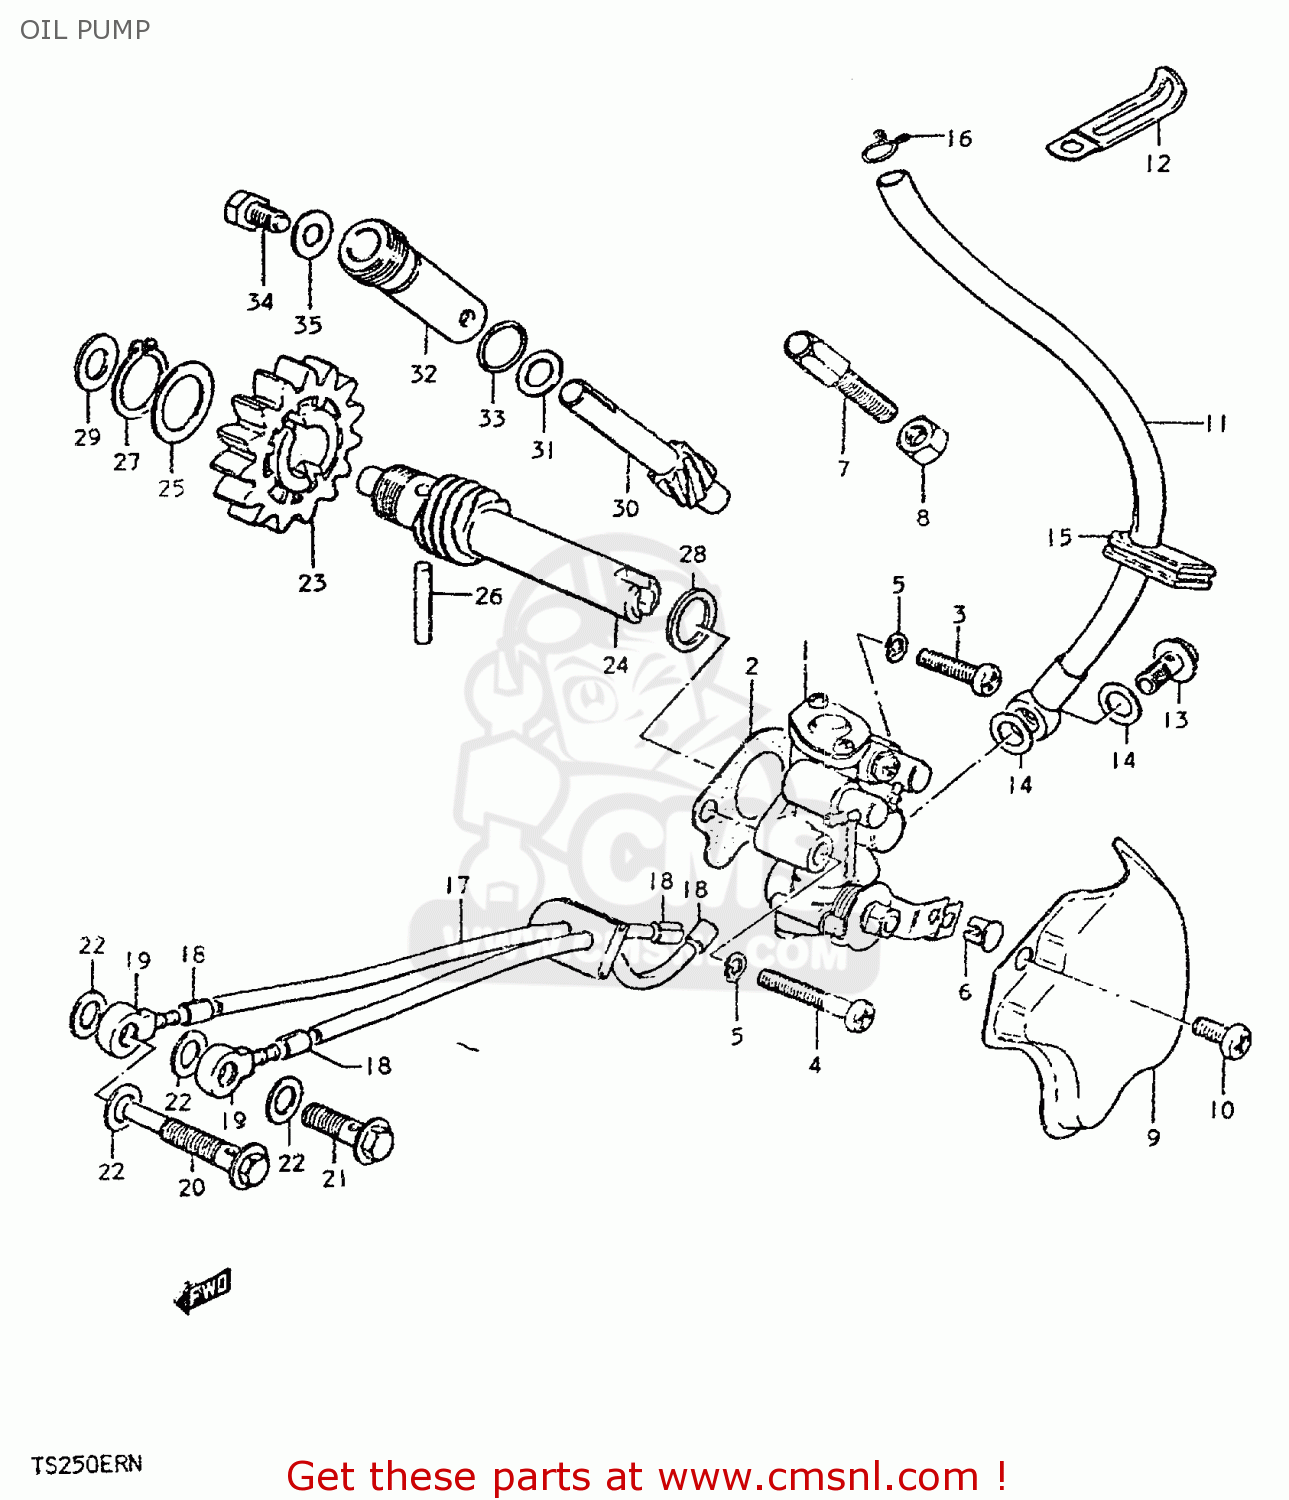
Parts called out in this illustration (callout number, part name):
1	PUMP ASSEMBLY,OIL
2	GASKET,OIL PUMP (NAS)
3	SCREW
4	SCREW
5	LOCK WASHER
6	TERMINAL,CABLE
7	BOLT
8	NUT
9	CAP,OIL PUMP INSPECTION
10	SCREW
11	HOSE,OIL NO.1
12	CLAMP
13	UNION BOLT
14	GASKET(6.2X11X1).2 (NAS)
15	GROMMET
16	CLIP
17	HOSE,OIL NO.2
18	CLIP
19	UNION
20	UNION
21	UNION BOLT
22	GASKET(6.2X11X1).2 (NAS)
23	GEAR,OIL PUMP DRIVE
24	SHAFT,OIL PUMP IDLE GEAR
25	WASHER, INNER
26	ROLLER(4X23.8)
27	CIRCLIP
28	WASHER
29	THRUST WASHER
30	GEAR,TACHOMETER DRIVEN
31	WASHER(8X13.7X1)
32	SLEEVE,TACHOMETER DRIVE
33	O RING(D:1.3,ID:9.6)
34	BOLT
35	WASHER
